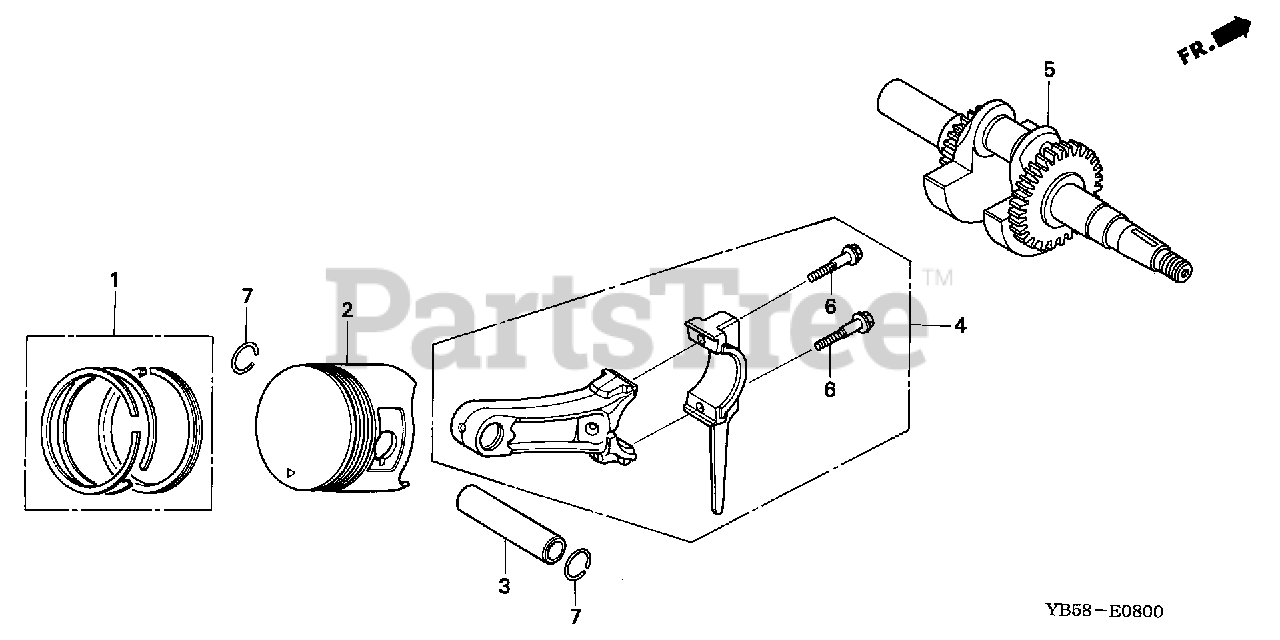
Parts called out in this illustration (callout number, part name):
1	RING SET, PISTON (STD) (TEIKOKU)
1	RING SET, PISTON (STD) (NIPPON)
1	RING SET, PISTON (0.25) (TEIKOKU)
1	RING SET, PISTON (0.25) (NIPPON)
1	RING SET, PISTON (0.50) (TEIKOKU)
1	RING SET, PISTON (0.50) (NIPPON)
1	RING SET, PISTON (0.75) (TEIKOKU)
1	RING SET, PISTON (0.75) (NIPPON)
2	PISTON (STD)
2	PISTON (0.25)
2	PISTON (0.50)
2	PISTON (0.75)
3	PIN, PISTON
4	ROD ASSY., CONNECTING (STD)
4	ROD ASSY., CONNECTING
4	ROD ASSY., CONNECTING (0.25 LOWER SIZE)
5	CRANKSHAFT
6	BOLT, CONNECTING ROD
7	CLIP, PISTON PIN (18MM)
